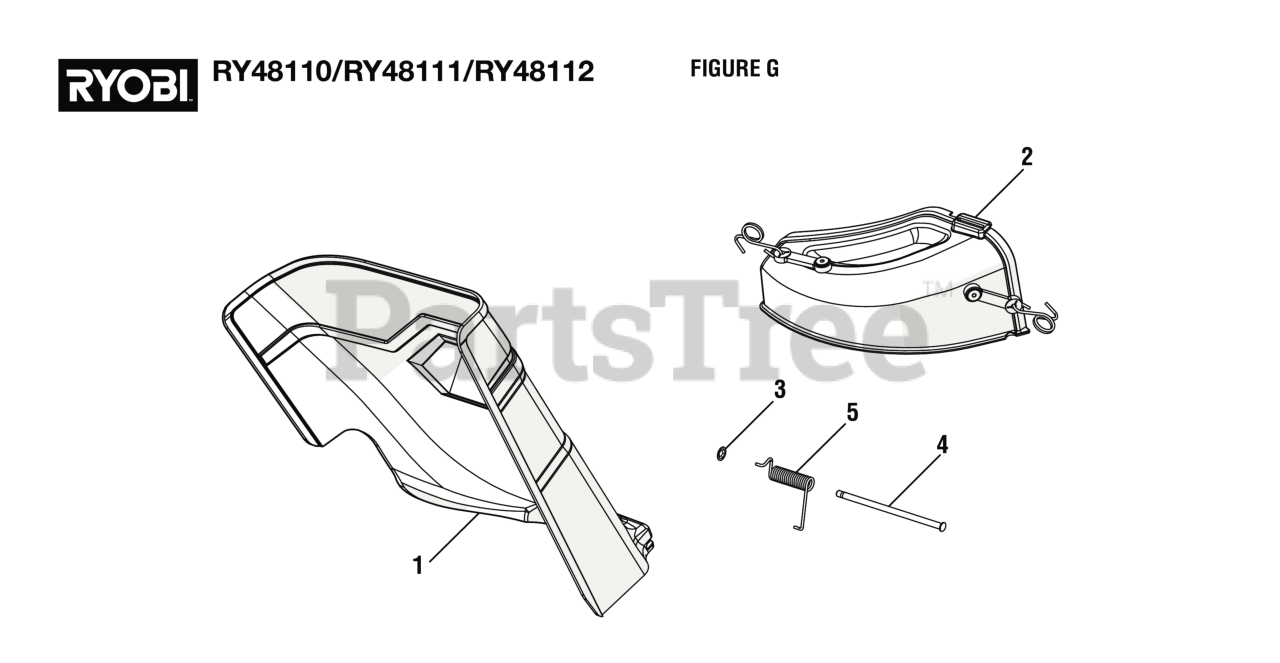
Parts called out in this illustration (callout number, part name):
1	Grass Deflector
2	Mulch Cover Kit
3	Retainer Clip
4	Hinge Pin (7.85 x 175.85)
5	Torsion Spring (19 x 62 x 3.02t)
